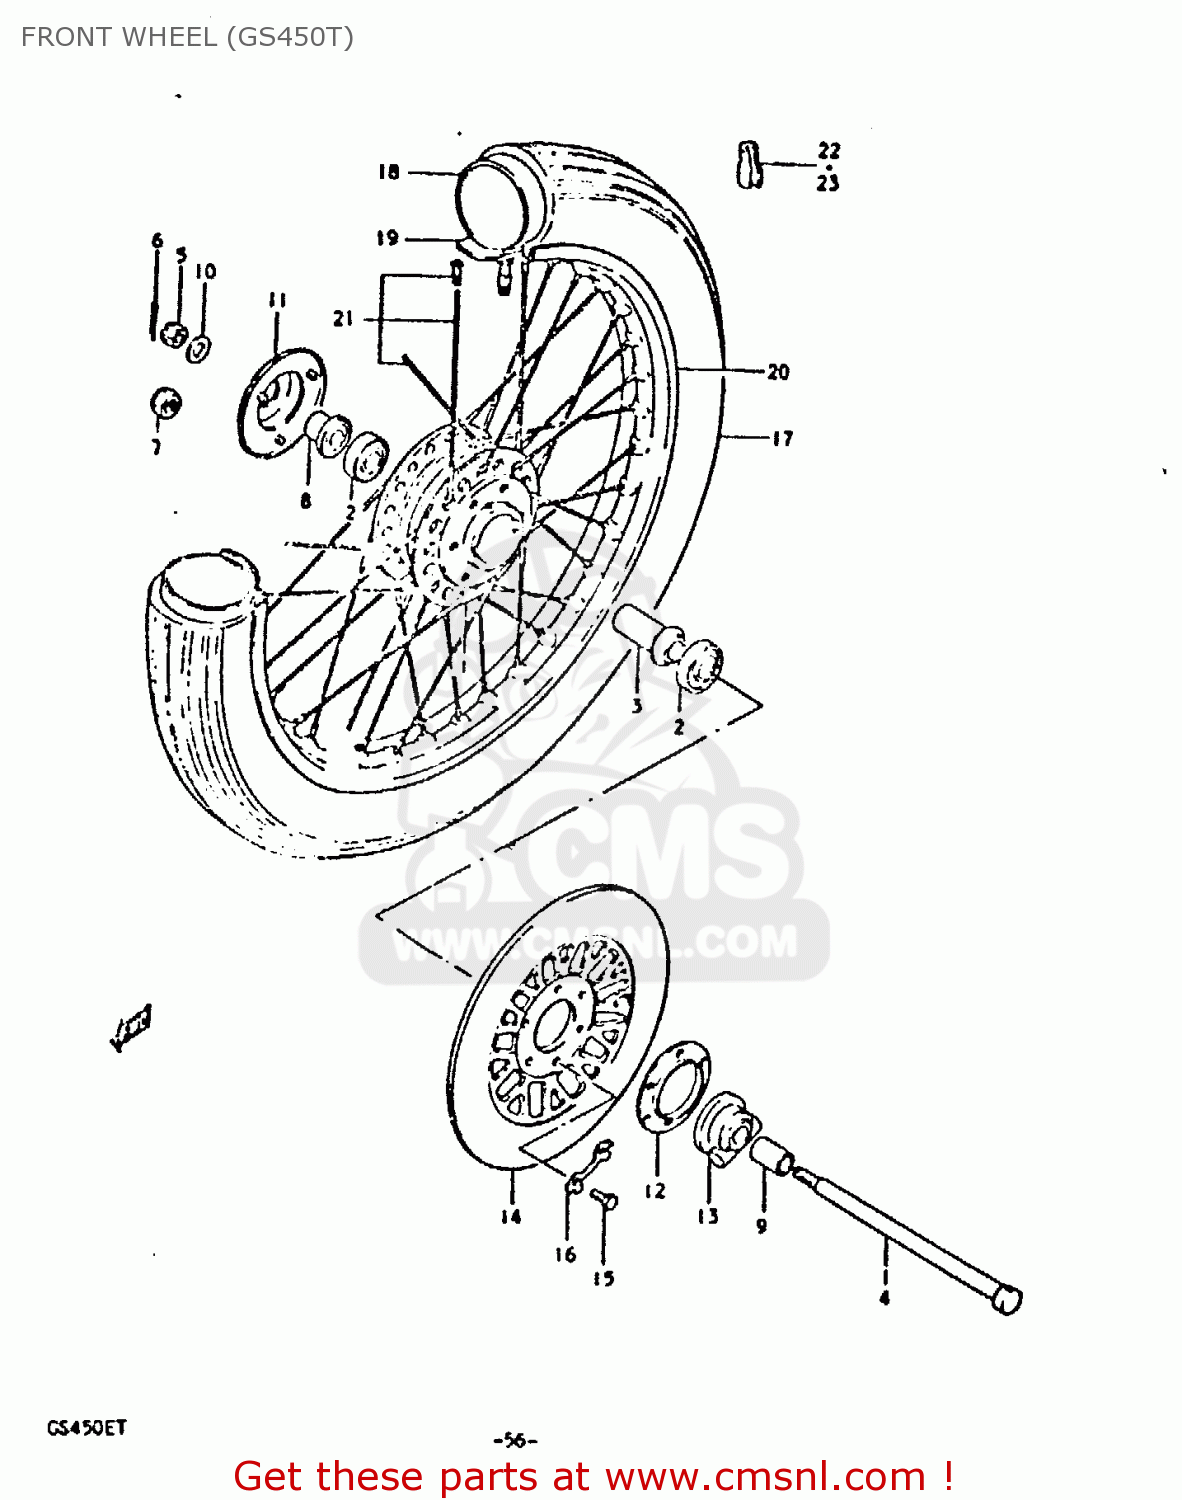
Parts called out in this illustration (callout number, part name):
1	DRUM,FRONT HUB
2	BEARING
3	SPACER,FR HUB BEARING
4	AXLE,FRONT
5	NUT 12MM
6	COTTER PIN
8	SPACER,FR HUB BEARING,R
9	SPACER(15X22X30)
10	WASHER
11	COVER,FR HUB,R
12	DUST SEAL,SPEEDOMETER GEAR BOX
13	BOX ASSY,SPEEDOMETER GEAR
14	DISC,FR BRAKE
15	BOLT(8X25)
16	WASHER
17	TIRE,FRONT
18	TUBE,INNER
19	PROTECTOR,WHEEL,INNER
20	RIM,FR WHEEL
21	SPOKE SET,FRONT
22	BALANCER,WHEEL (B)
23	BALANCER,WHEEL (30G)
